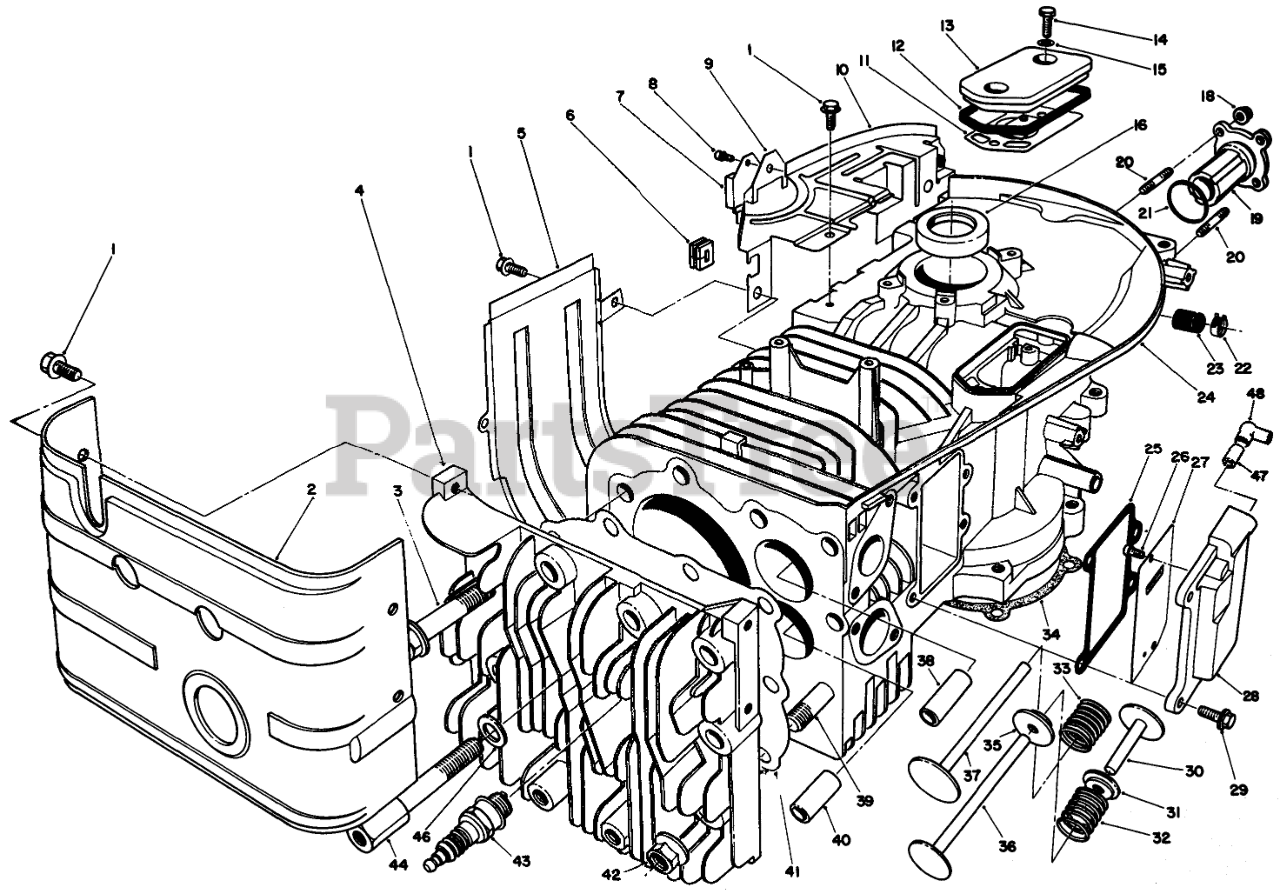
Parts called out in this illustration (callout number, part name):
1	Bolt-Flanged (6X10)
3	Bolt
4	Cylinder Head
7	Igniter
10	Fan Housing
14	Bolt
16	Seal-Oil
18	Nut
19	Shaft
24	Crankcase Assembly
28	Cover-Valve Chamber
29	Bolt-Flanged (6X16)
31	Retainer-Spring
32	Spring-Valve
33	Spring-Valve
36	Exhaust Valve
37	Intake Valve
38	Guide-Intake Valve
40	Guide-Exhaust Valve
41	Gasket
43	Spark Plug
46	Washer
